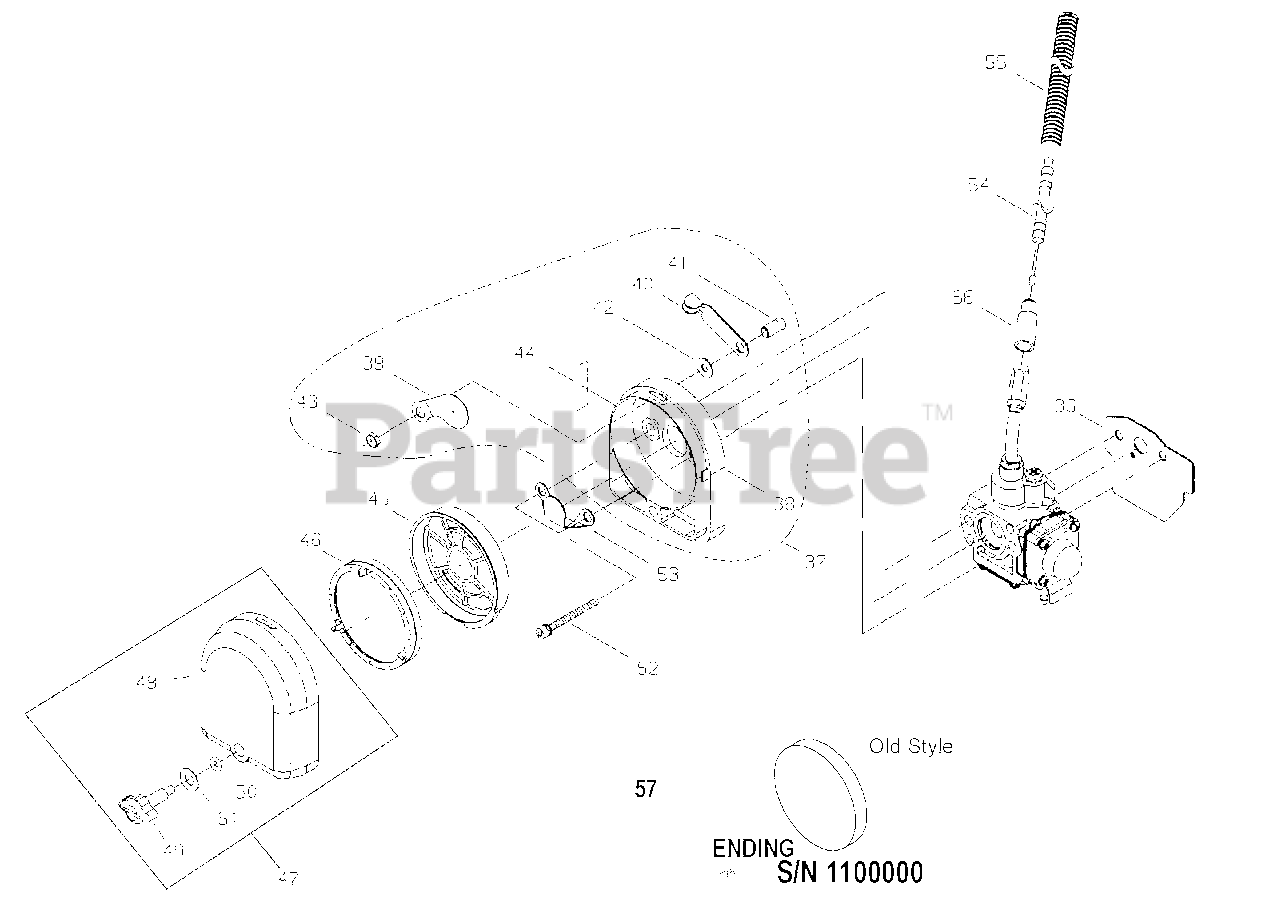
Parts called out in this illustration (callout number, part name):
6	GASKET, CARBURETOR
37	CASE ASSY, AIR FILTER
38	CASE, AIR FILTER
39	PLATE, CHOKE
40	LEVER, CHOKE
41	SHAFT, CHOKE
42	WASHER, CONE M6
43	U-NUT M6
44	LABEL, CHOKE
45	SCREEN, REAR AIR FILTER
46	FILTER, HEAVY-DUTY AIR
47	COVER ASSY, AIR FILTER
48	COVER, AIR FILTER
49	THUMBSCREW
50	O-RING
51	WASHER, CONE M6
52	BOLT M5×50
53	PLATE
54	CABLE, THROTTLE
55	TUBE, PLASTIC PROTECTIVE
56	CAP, CARBURETOR
57	FILTER, AIR
